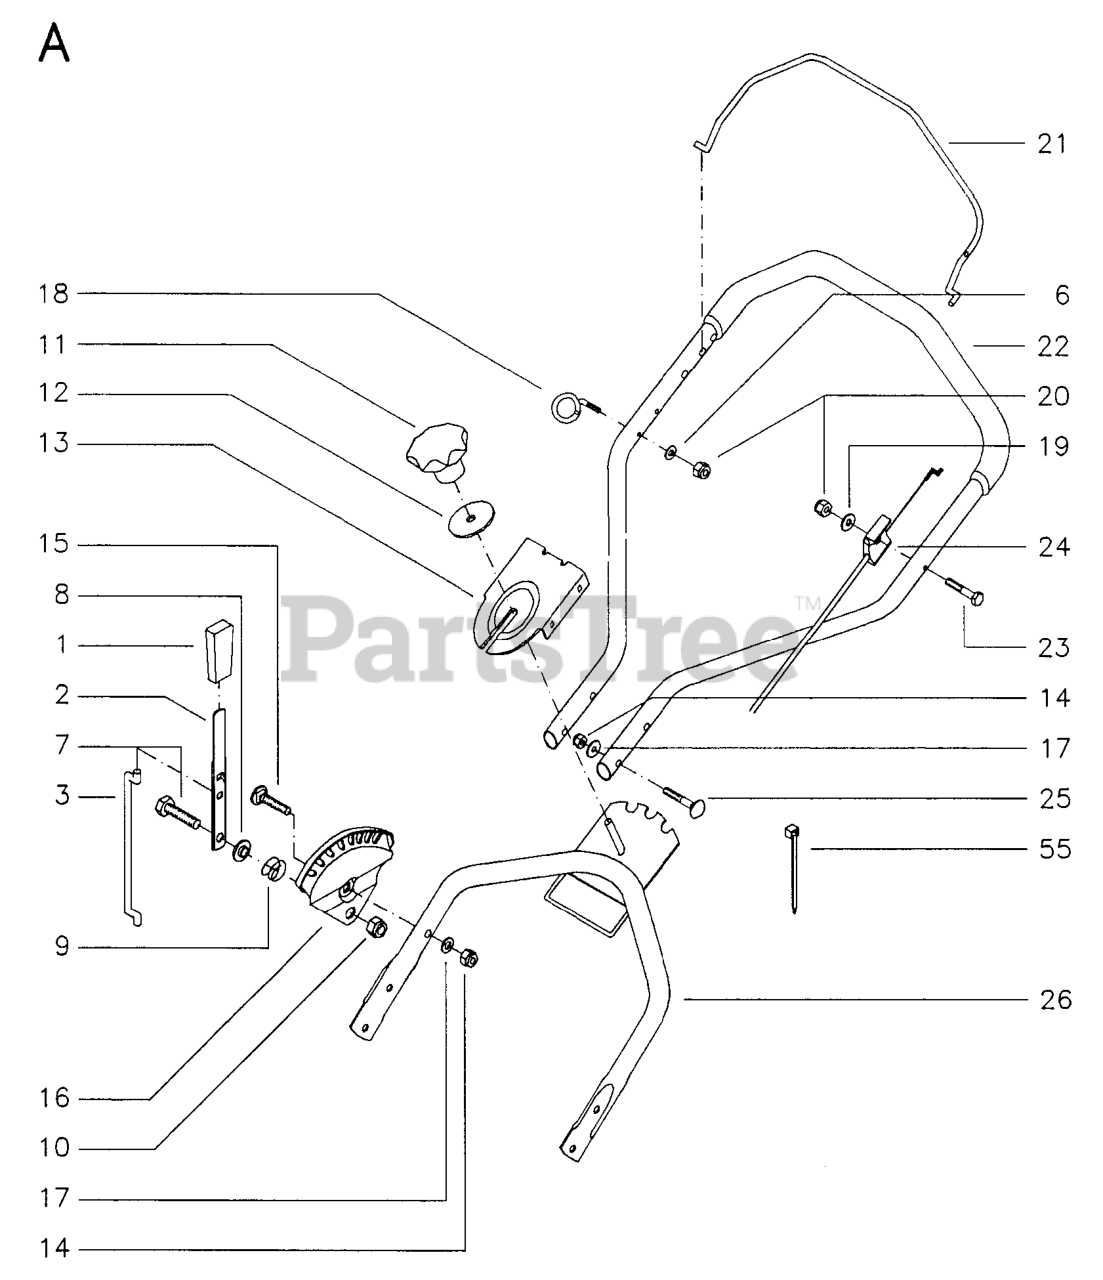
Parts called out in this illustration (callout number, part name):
2	CLUTCH ARM
9	PRESSURE SPRING
14	LOCKNUT M8
16	INDEXPLATE
17	WASHER - 15X7.3X1.6
18	CABLE GUIDE
20	LOCKNUT M6
23	BOLT FLANGE
